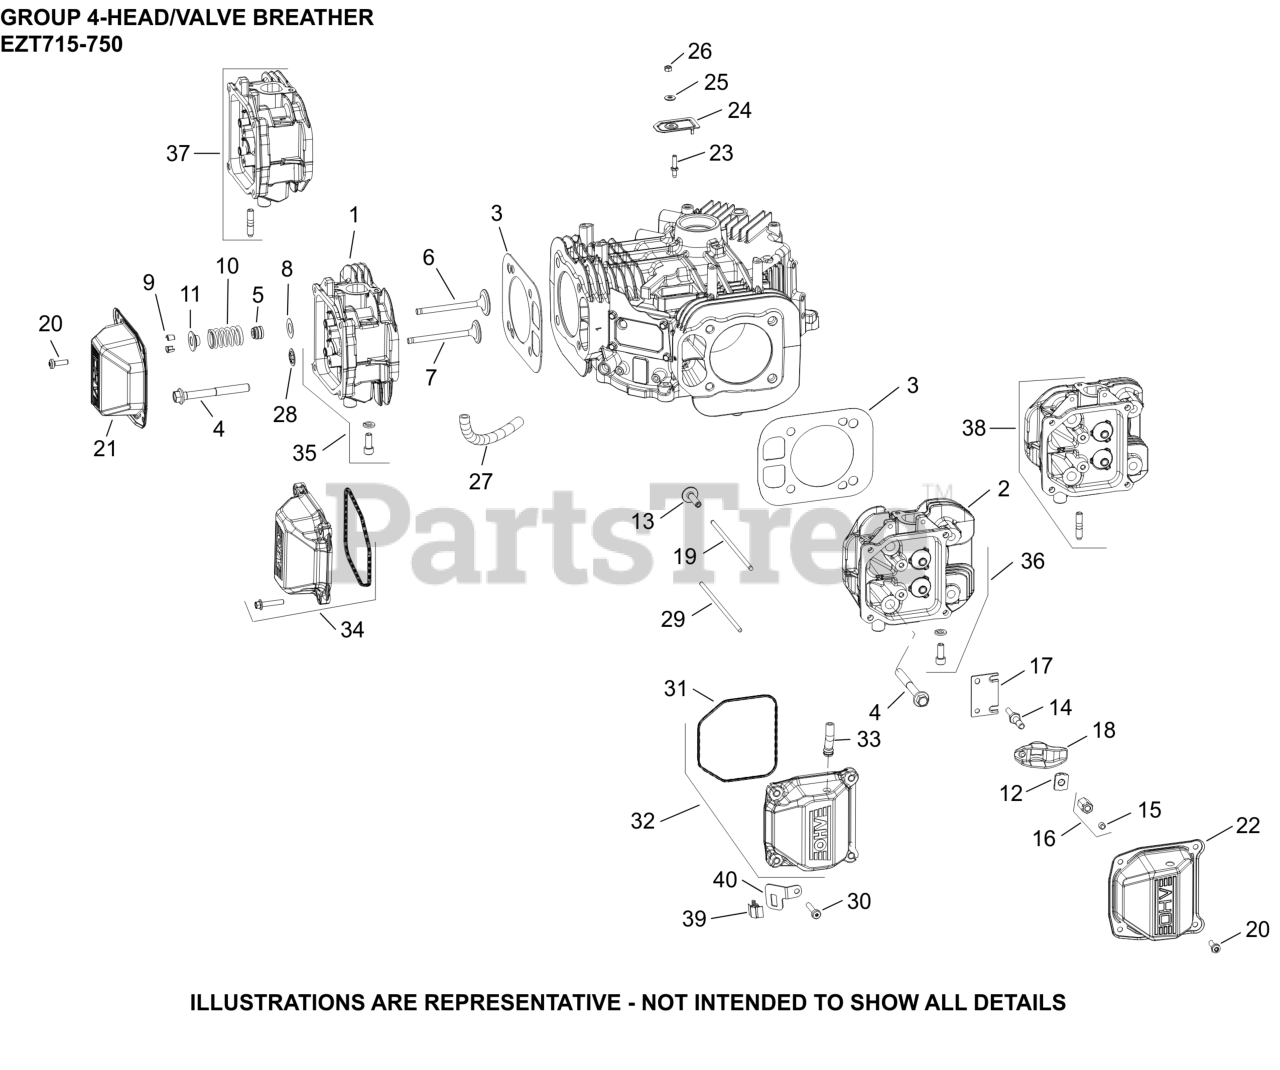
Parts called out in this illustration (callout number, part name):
1	HEAD, ASSY CYLINDER (#1)-USE 16 755 10-S
2	HEAD, ASSY CYL (#2)-USE 16 755 11-S
3	KIT, GASKET CYLINDER HEAD
4	SCREW, FLG M10X1.5X90
5	SEAL, VALVE BAND
6	VALVE, INTAKE
6	VALVE, INTAKE (.25) - (#2401702S)
7	VALVE, EXHAUST
7	VALVE, EXHAUST (.25)
8	SPACER (.010")
9	KIT, RETAINER
10	SPRING VALVE
11	CAP, VALVE SPRING
12	PIVOT, ROCKER ARM
14	STUD, ROCKER
15	SCREW, SET
16	HEX NUT ASSEMBLY
17	PLATE, GUIDE
18	ARM, ROCKER
19	ROD, PUSH
20	SCREW, PAN HEAD
21	COVER, ROCKER STAMPED STEEL
22	COVER, ROCKER STAMPED STEEL
24	COVER, BREATHER REED
25	WASHER, SEALING
26	NUT, LOCK M5X.8
27	HOSE, BREATHER
28	RETAINER, VALVE GUIDE (KM)
35	KIT,HEAD #1 AND HARDWARE-USE 16 755 20-S
36	KIT, HEAD #2 AND HARDWARE-(#1675521S)
